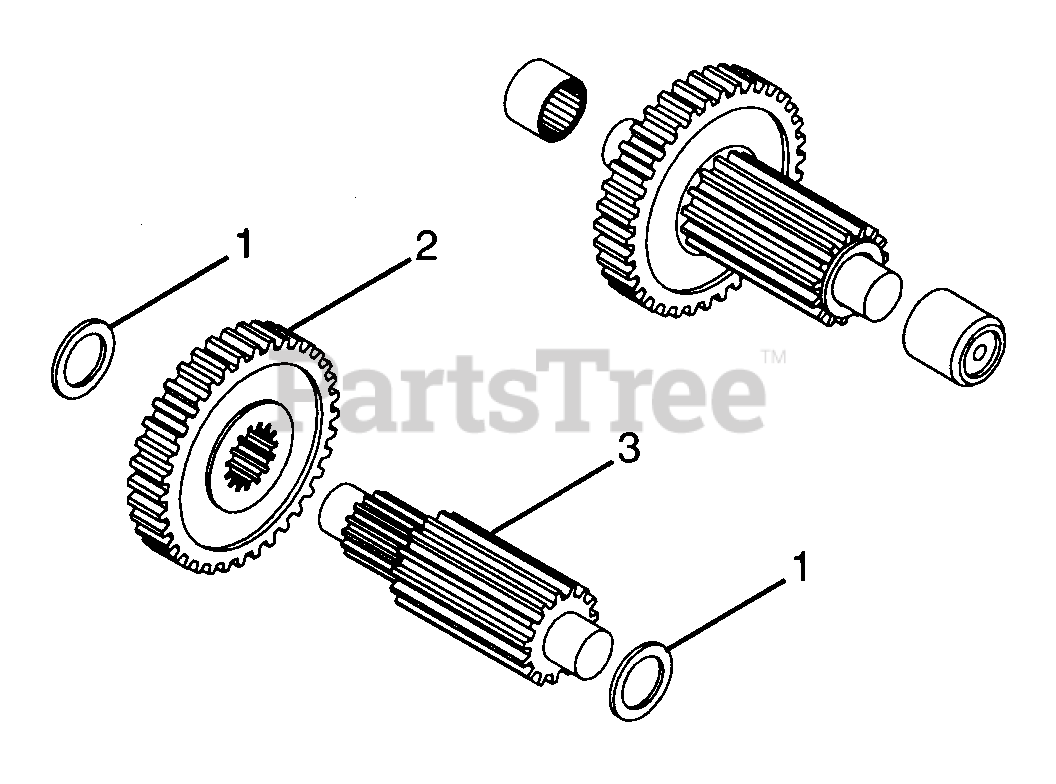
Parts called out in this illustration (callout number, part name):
1	Washer-Hardened-Thrust 1.002 x 1.552 x .030
2	Gear 8 DP 30 Teeth x .750
3	Pin-Final Drive
